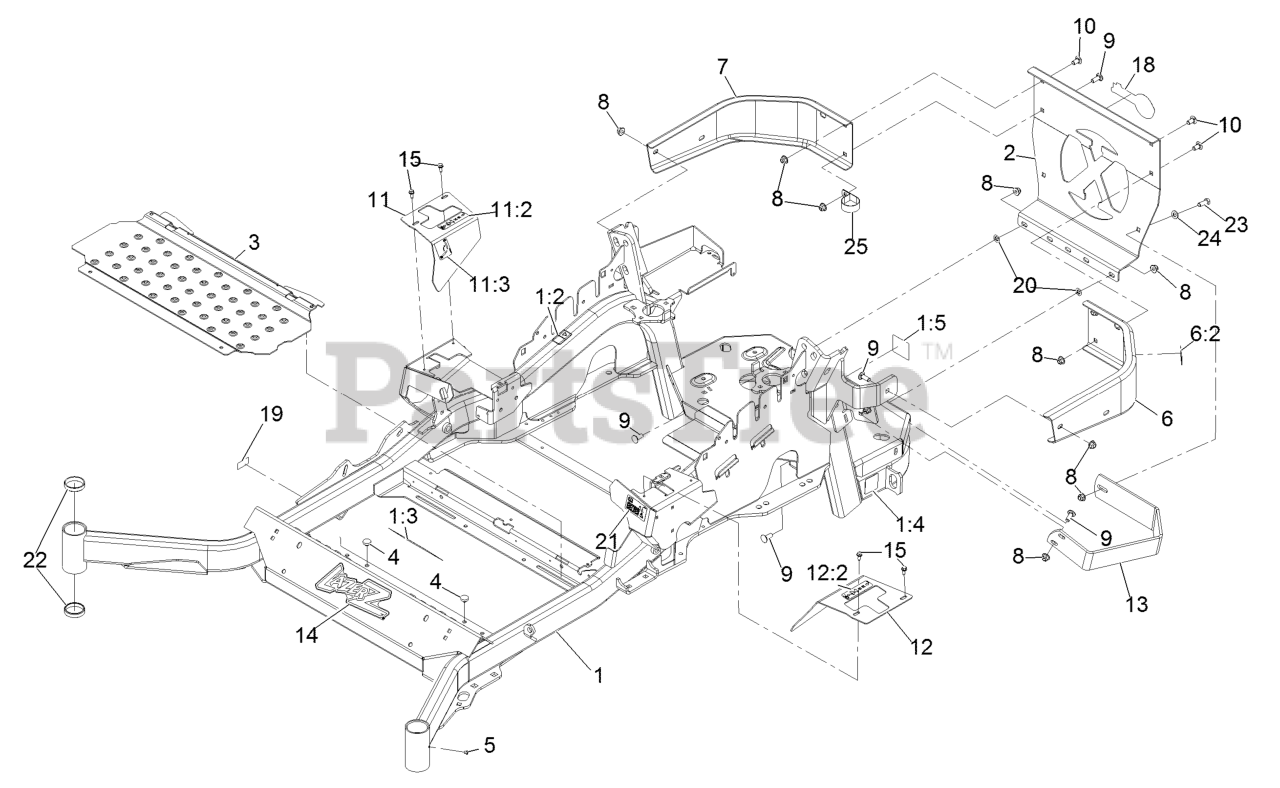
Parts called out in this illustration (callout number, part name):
1	MAINFRAME ASM
1:2	DECAL-WARNING
1:3	DECAL-WARNING, SLOPE
1:4	DECAL-HAZARD, PINCHED FINGER
1:5	DECAL-SPARK ARRESTER
2	PLATE,REAR GUARD
6	LH BUMPER ASM
6:2	DECAL-WARNING
7	BUMPER-RH
8	NUT-HF, NI
9	SCREW-CARR
10	SCREW-CARR
11	RH MOTION CONTROL COVER ASM
11:2	DECAL-CONTROL, MOTION
11:3	DECAL-PARK BRAKE, CE
12	LH MOTION CONTROL COVER ASM
12:2	DECAL-CONTROL, MOTION
13	GUARD-MUFFLER
14	DECAL,LAZER MODEL
15	SCREW-HWH
19	Decal-Patent Ttco.Com
20	NUT-PUSH
21	DECAL-FUEL FILL, CE
22	CUP-BEARING
23	SCREW-HH
24	WASHER-FLAT
25	CLAMP-R
